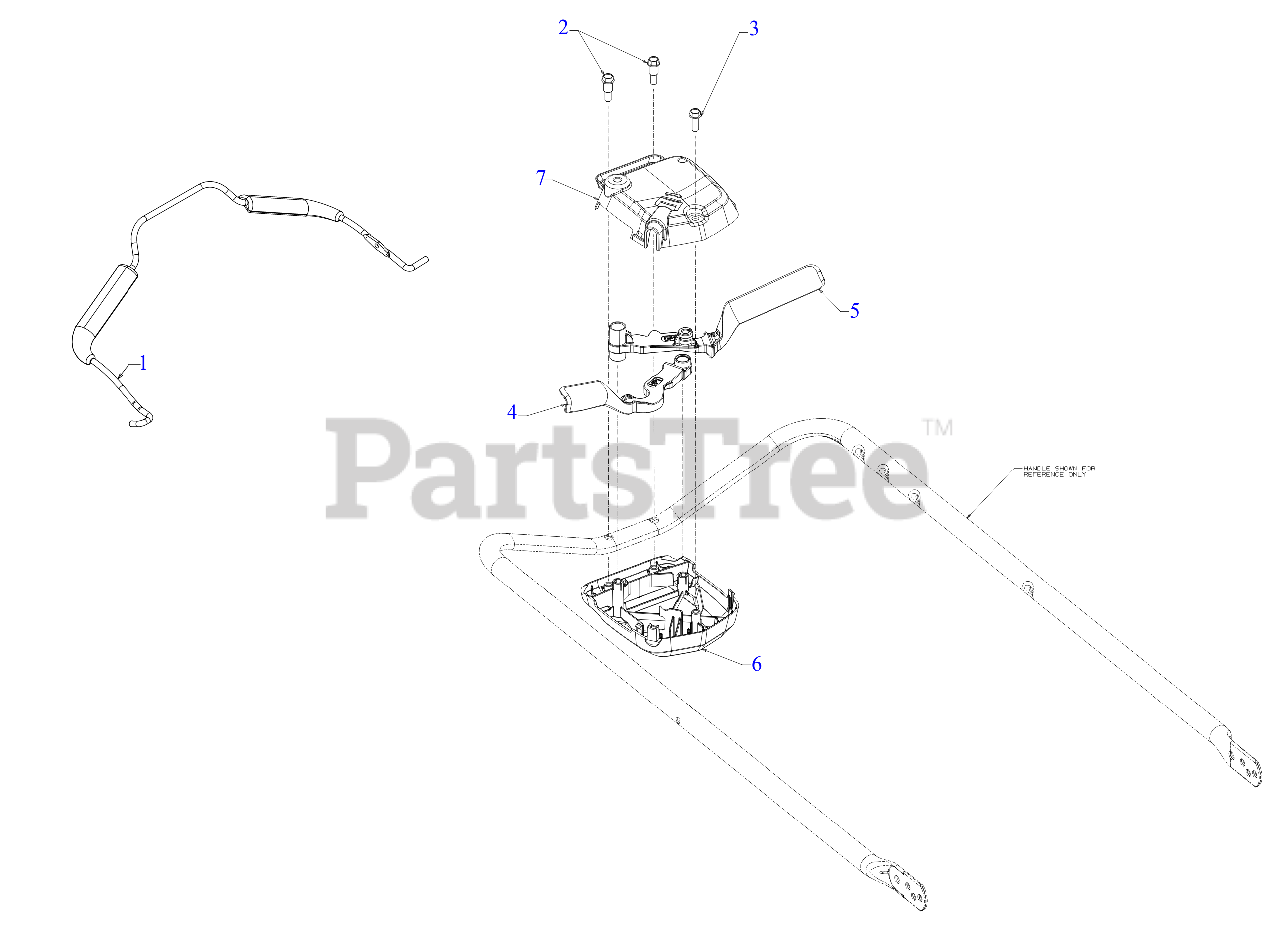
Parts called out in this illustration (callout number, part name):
1	OPERATOR BAIL
2	SHOULDER SCREW 1/4-15 x .970
3	SCREW 1/4-15 x .750
4	CONTROL LEVER (LH)
5	CONTROL LEVER (RH)
6	UPPER CONTROL HOUSING
7	LOWER CONTROL HOUSING
